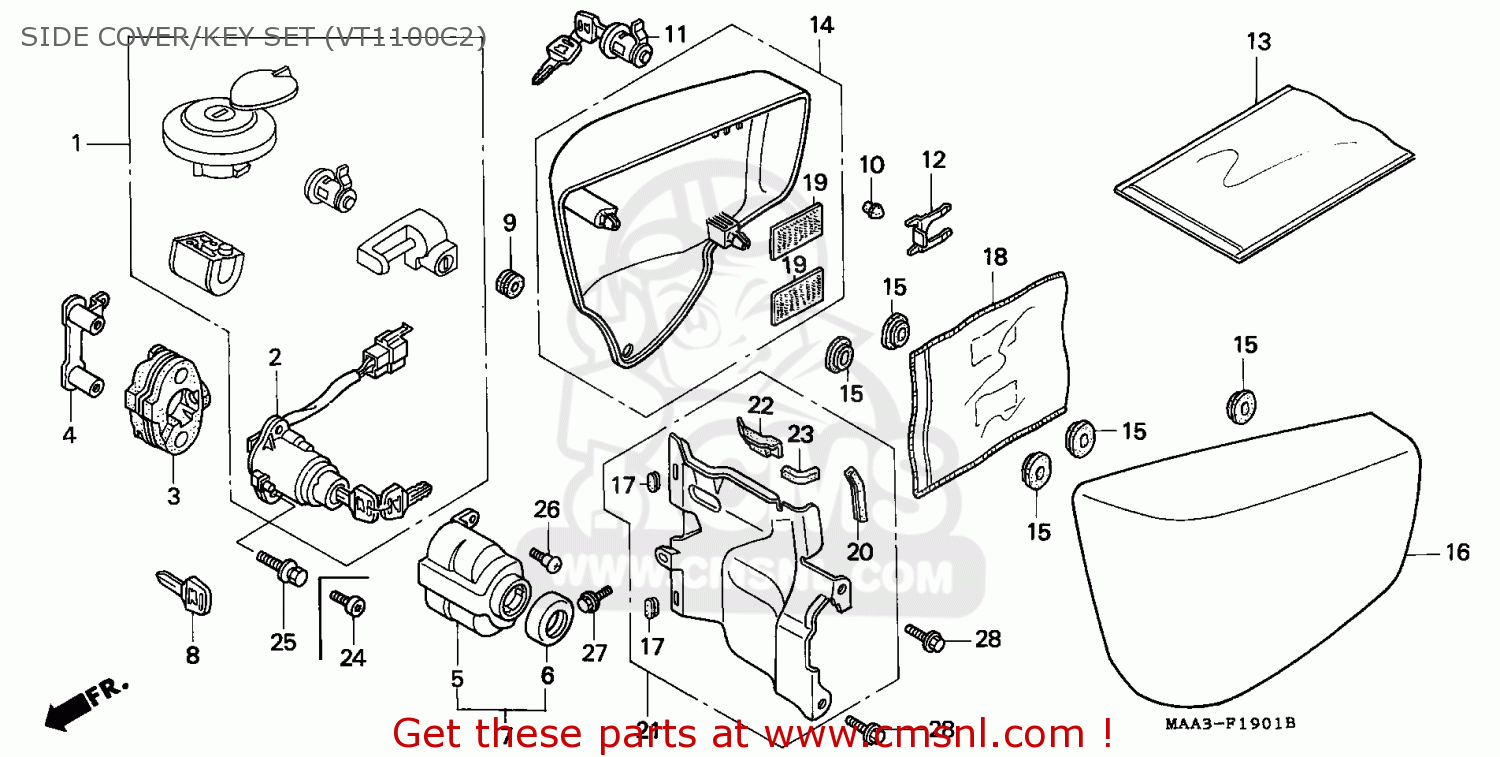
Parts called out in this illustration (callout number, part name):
1	KEY SET
2	SWITCH ASSY,COMB
3	BASE,COMBI SW
4	COLLAR,COMBINATIO
5	COVER,COMBINATION
8	KEY,BLANK (NO.1)
9	GROM SIDE COVER
10	CAP,STEP HOLDER E
11	LOCK ASSY,POCKET
12	SPG.,KEY SET COCK
13	BAG,SERVICE BOOK
14	COVER R,SI*TYPE1*
15	CASE,GROMET
16	COVER L,SI*TYPE1*
17	GROM.SIDE COVER
18	BAG,OWNERS MANUAL
19	TAPE,MAGIC (FEMAL
20	RUBBER,PROTECTER
21	COVER ASSY.,CENTE
22	RUBBER,PROTR.C
23	RUBBER,PROTECTERD
25	BOLT,BREAK OFF
26	SCREW,RR,COVER
27	BOLT,FLANGE,6X8
